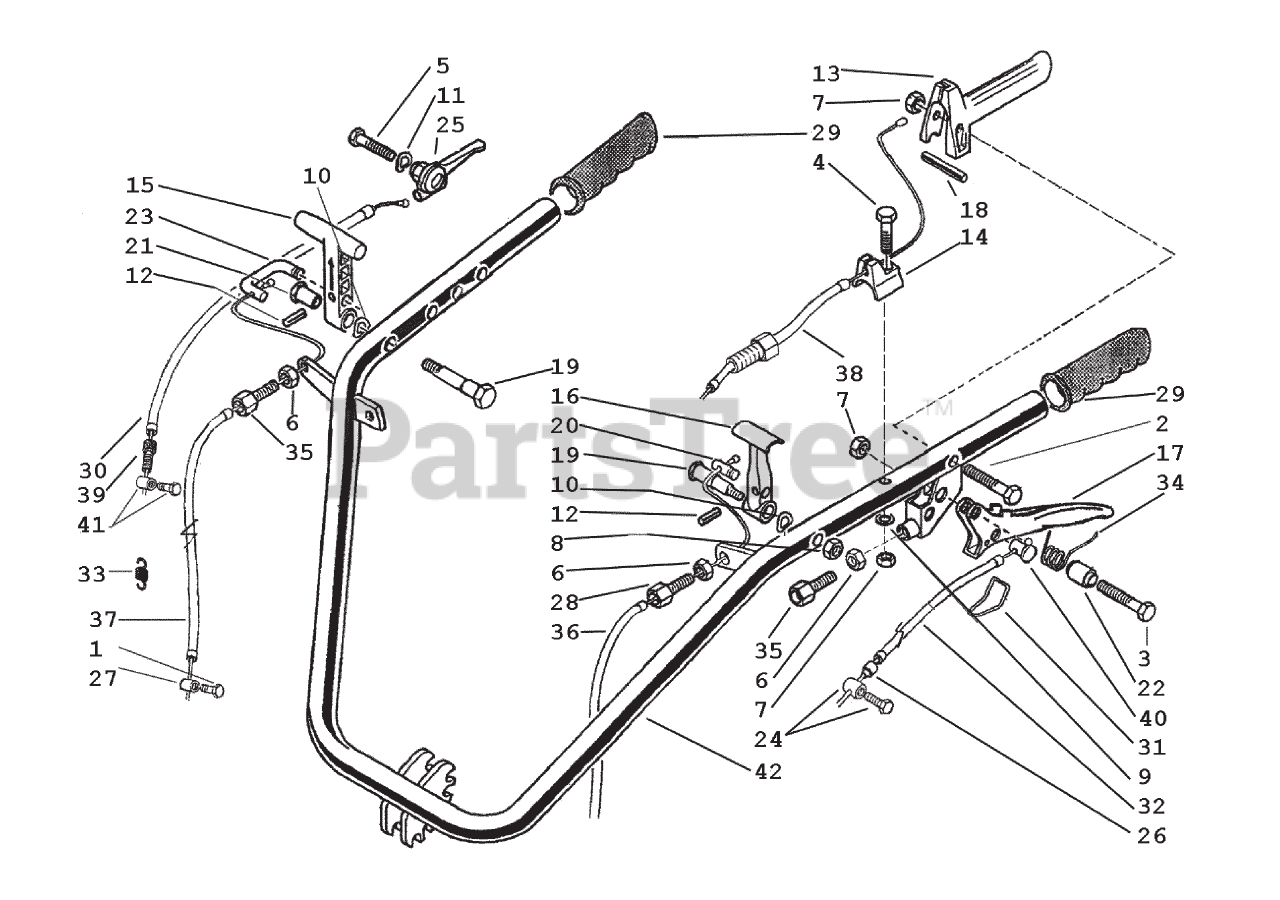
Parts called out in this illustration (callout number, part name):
1	CAP SCREW, M6X16
2	CAP SCREW, M6X45
3	CAP SCREW, M6X25
4	CAP SCREW, M6X35
5	CAP SCREW, M8X35
6	NUT, M8
7	LOCK NUT, M6
8	LOCK NUT, M8
9	FLAT WASHER, M6
10	FLAT WASHER, M8
11	LOCK WASHER, M8.4
12	PIN, SPLIT, M4 X 20 SPIROL
13	LEVER, MOTOR STOP
14	GUIDE, CABLE
15	LEVER, REVERSER
16	LEVER, STEERING COL. RELEASE
17	LEVER, CLUTCH
20	DRILLED PIN
21	BUSHING, REVERSE LEVER
22	LEVER, SPACER
23	PIN, REVERSE CABLE
24	CABLE CLAMP
25	ACCELERATOR LEVER
26	SHEATH END
27	CLAMP
28	SCREW, ADJUSTING M8
30	CABLE, ACCELERATOR, 73SHX7
31	STOP WIRE
32	CABLE
33	SPRING
34	SPRING
35	SCREW, ADJUSTMENT
36	CABLE & SHEATH, STEERING COLUMN RELEASE
37	CABLE AND SHEATH
38	CABLE, MOTOR STOP
39	SCREW, ADJUSTING M6
40	BARREL
41	CLAMP
42	HANDLEBAR COMPLETE
